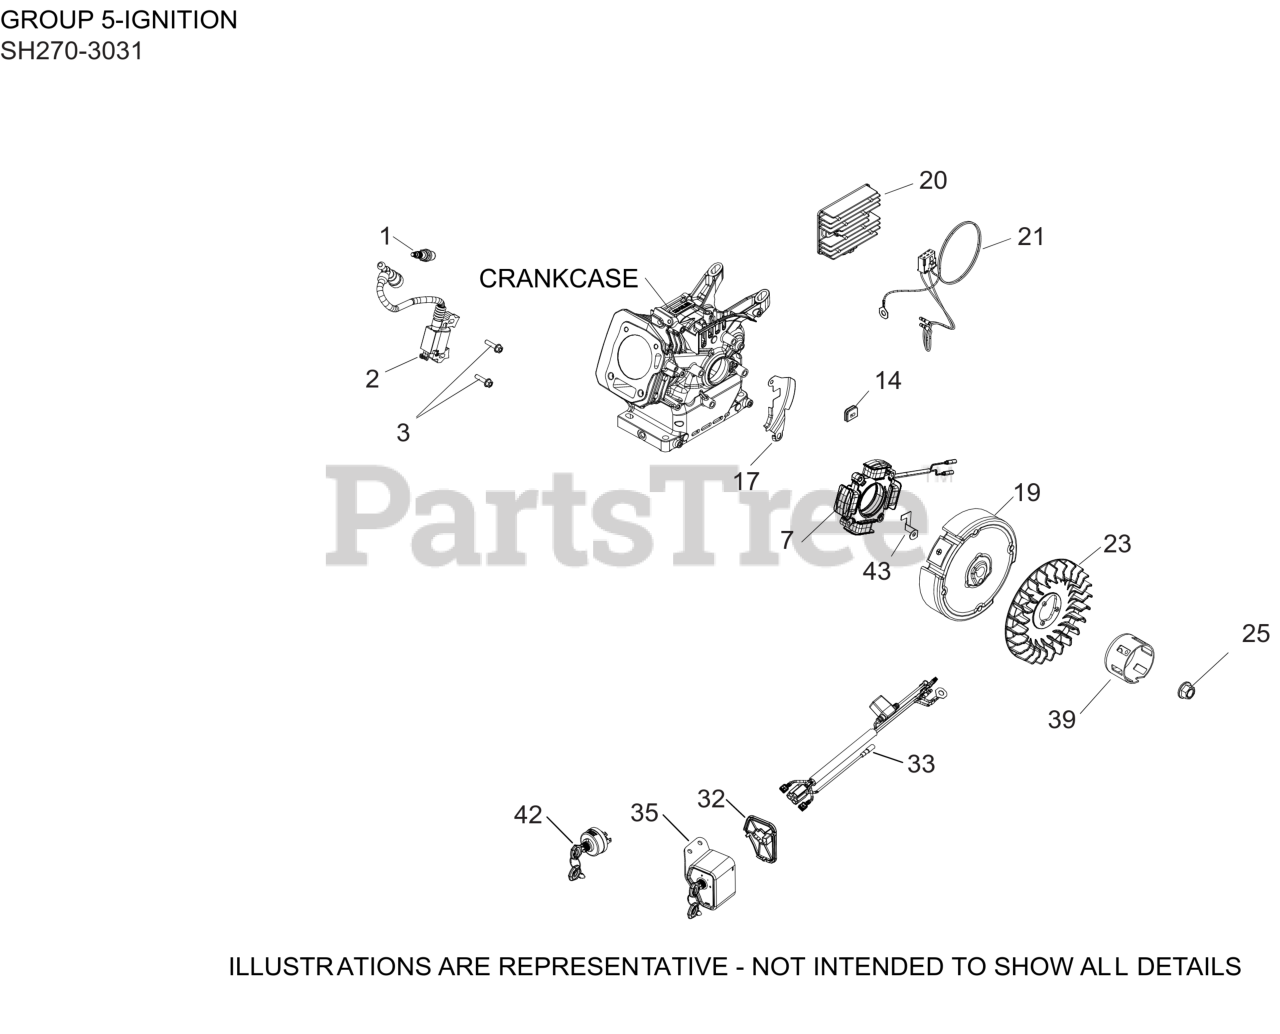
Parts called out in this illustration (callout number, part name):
1	SPARK PLUG
2	MODULE, IGNITION
3	SCREW, M6 X 25-(#25086436S)
7	STATOR ASSEMBLY, 3 POLE
14	GROMMET, STATOR WIRE
17	SHIELD, FLYWHEEL ASSEMBLY
19	FLYWHEEL ASSEMBLY - 10 AMP
20	REGULATOR, 10 AMP
21	HARNESS, REGULATOR WIRING ASSY
23	FAN, FLYWHEEL
25	NUT, FLYWHEEL (W/SERRATIONS)
32	COVER, KEY BOX
33	HARNESS, WIRING ASSEMBLY (10 AMP)
35	KIT, KEYBOX HOUSING ASSEMBLY
35	KIT, KEY BOX ASSEMBLY
39	STARTER CUP
42	SWITCH, KEY ASSEMBLY
43	BRACKET, FIXED STATOR WIRE
NI	KIT, KEY PLASTIC HANDLE (2 PC)
